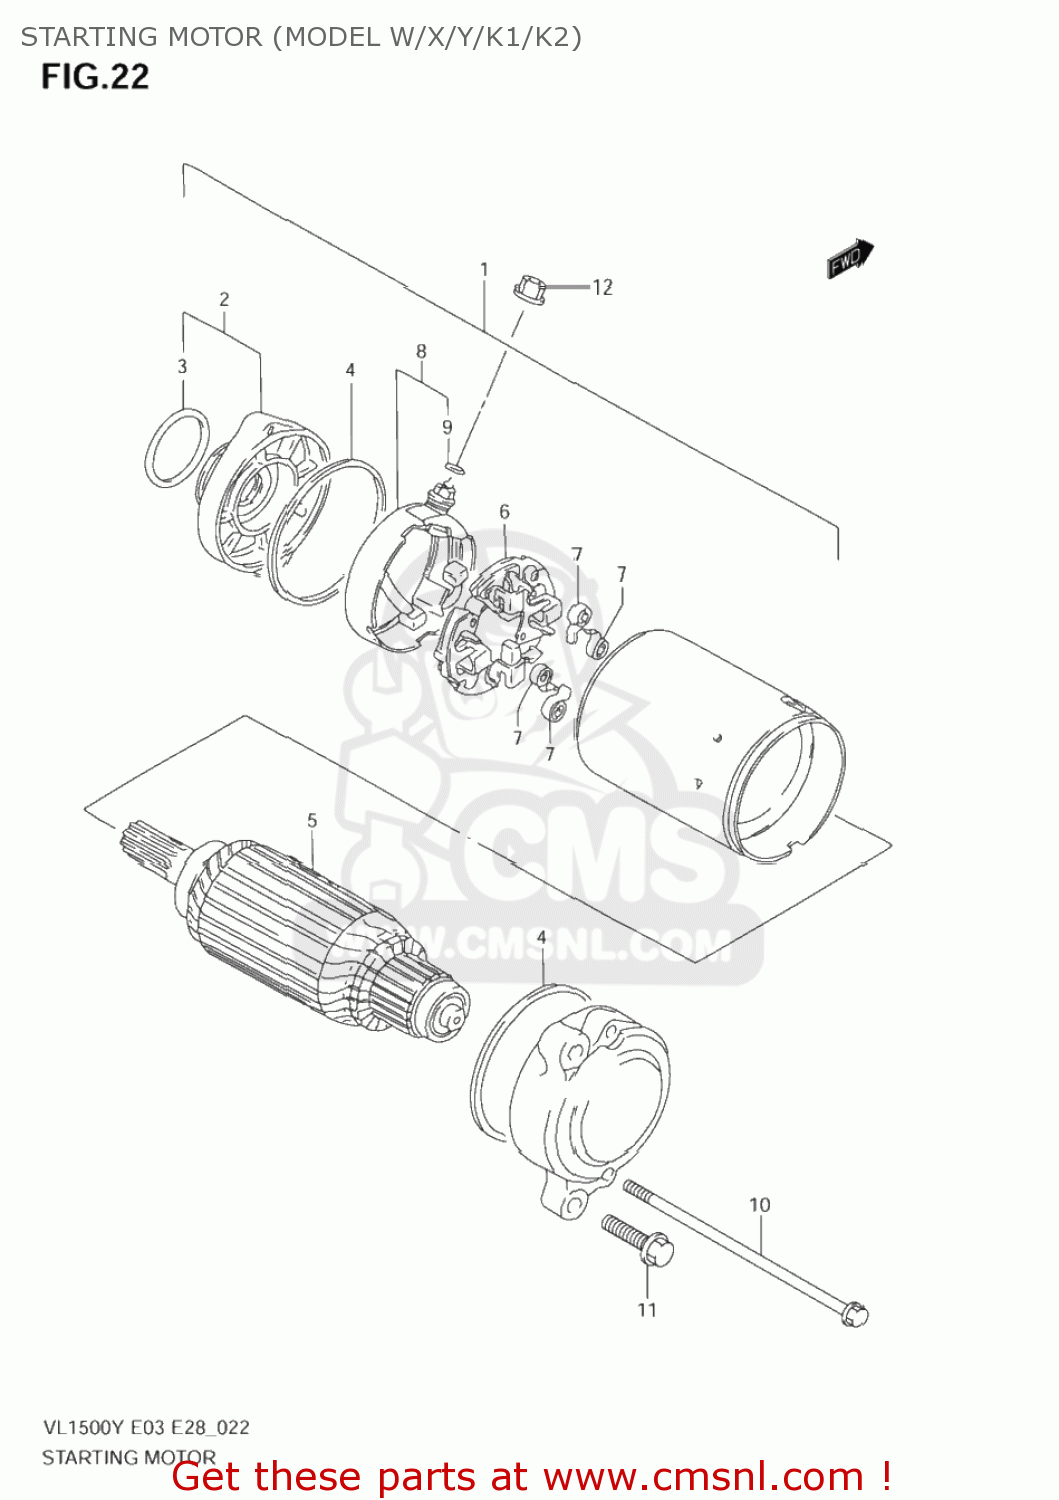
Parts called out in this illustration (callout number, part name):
1	MOTOR ASSY,STARTING
2	BRACKET SET
3	O-RING
4	O RING
5	ARMATURE
6	HOLDER SET,BRUSH
7	SPRING,BRUSH
8	TERMINAL SET,BRUSH
9	O RING
10	BOLT
11	BOLT
12	NUT
